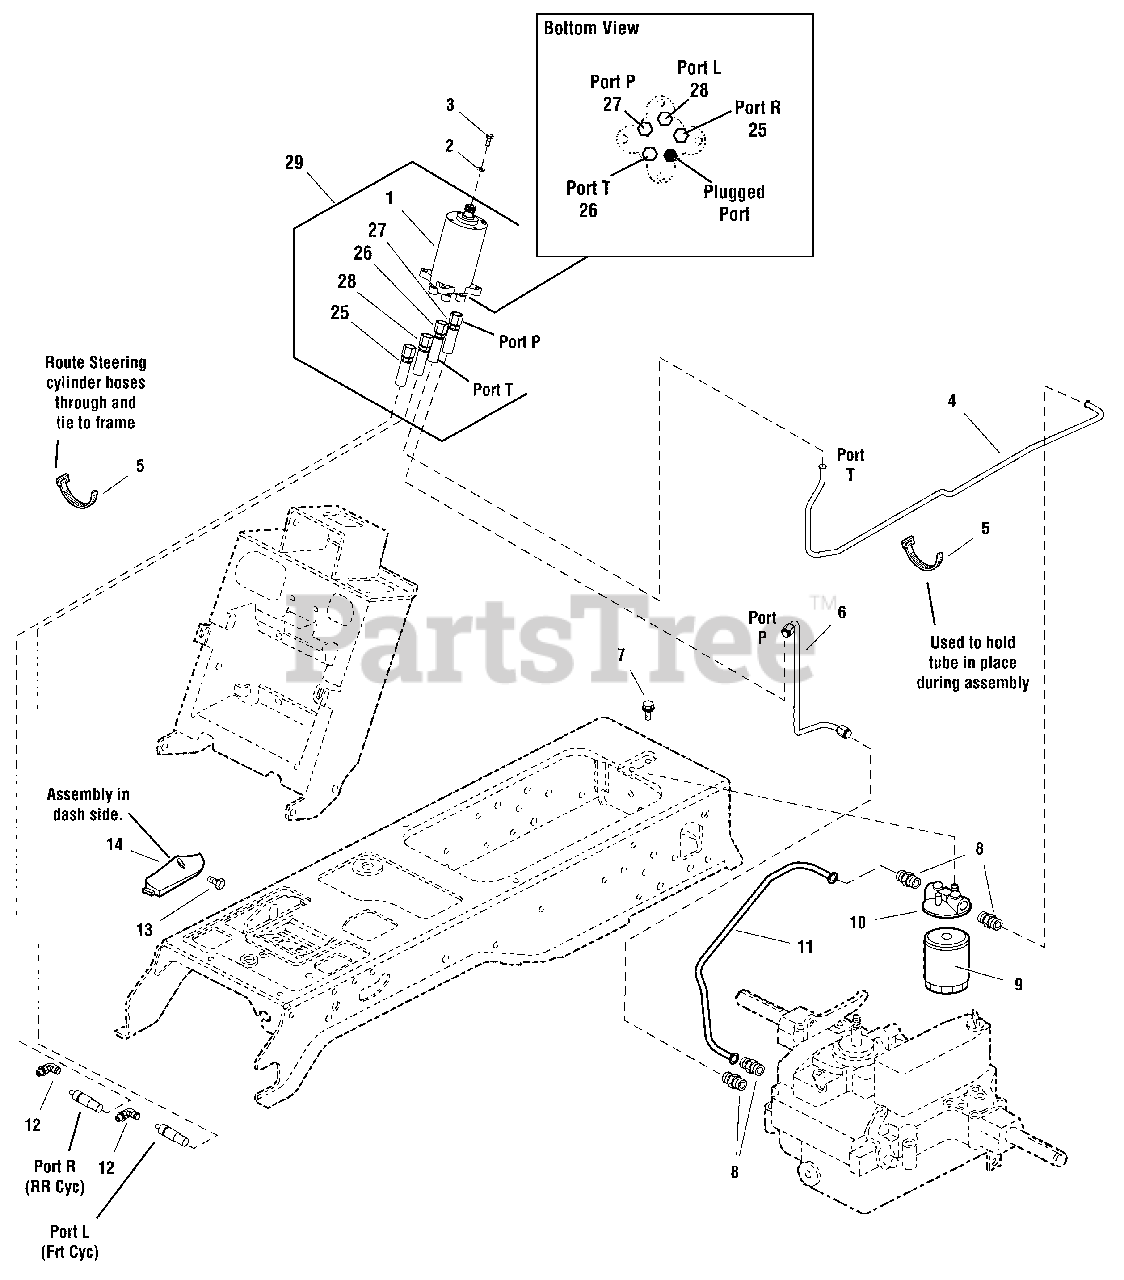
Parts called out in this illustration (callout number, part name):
1	POWER STEERING UNIT
2	LOCKWASHER, Spring 1/4
3	CAPSCREW, Hex Head, M06-1 x 16mm
4	TUBE, Hydraulic
5	TIE, Wire
6	TUBE, Hydraulic, Steel
7	SCREW, Whiz Lock, 1/4-20 x 1/2
8	FITTING, Straight
9	FILTER, Oil
10	MANIFOLD, Oil Filter
11	TUBE, Hydraulic
12	PERMA, Push FItting
13	SCREW, Rd Hd, Plastite #8
14	COVER, Lift
25	HOSE, Hydraulic, 27"
26	HOSE, Hydraulic, 18"
27	HOSE, Hydraulic, 26"
28	HOSE, Hydraulic, 31"
29	POWER STEERING ASSEMBLY, 4 Ports, 4WD
